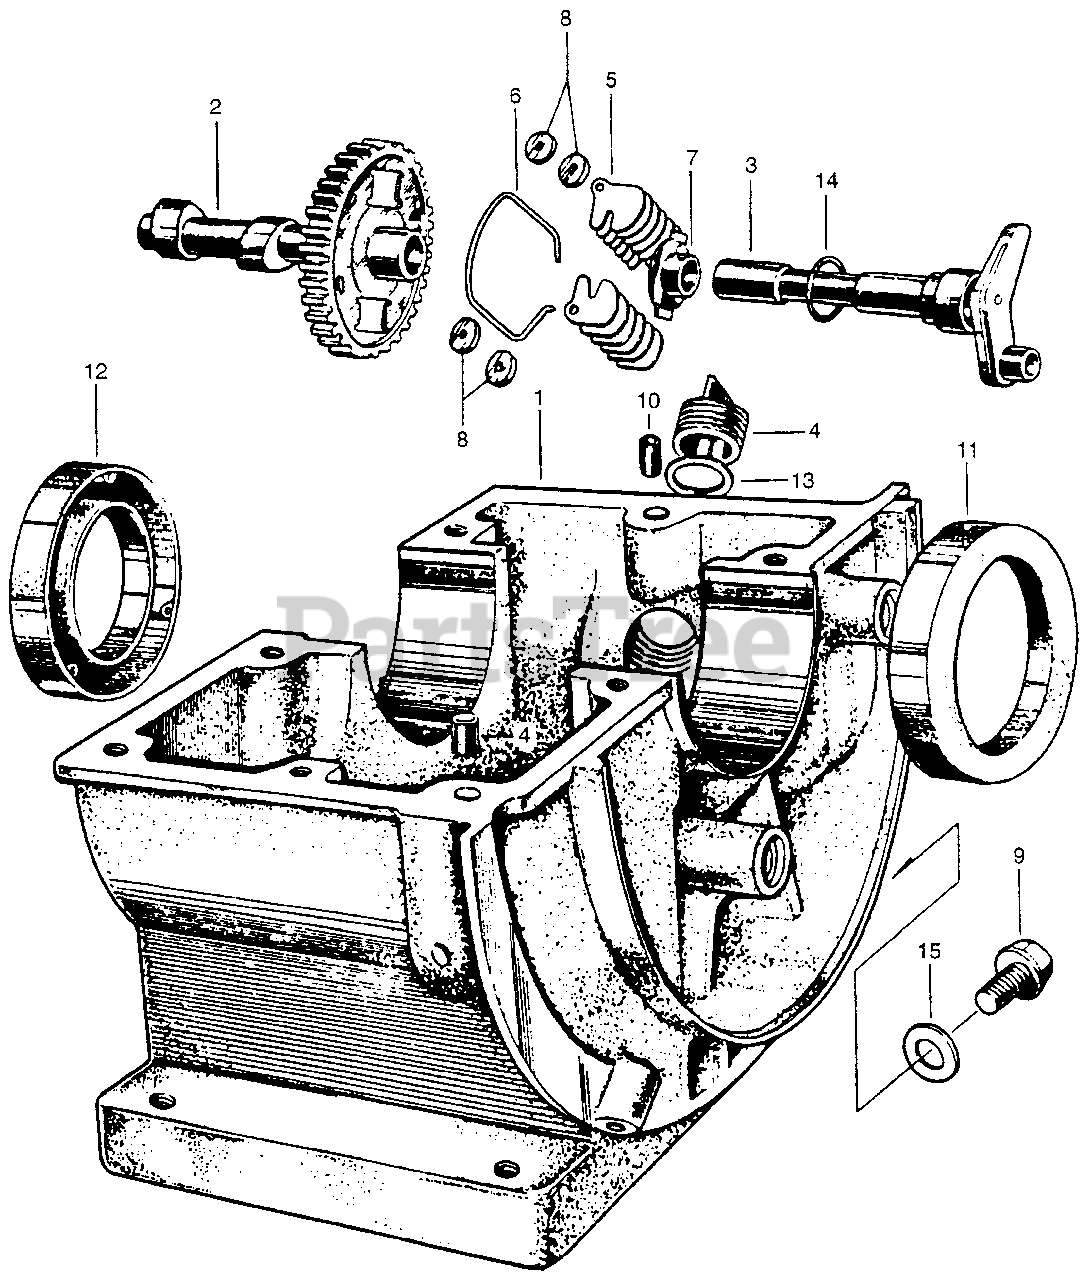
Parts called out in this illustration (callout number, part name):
1	PAN, OIL
3	CENTER, CAMSHAFT (NOT AVAILABLE)
4	CAP, OIL (YELLOW)
5	WEIGHT, GOVERNOR
6	CENTER, GOVERNOR WEIGHT
7	SLIDER, GOVERNOR
8	COLLAR, DISTANCE
9	BOLT, DRAIN PLUG
10	PIN, KNOCK (8.5X11) (NOT AVAILABLE)
11	OIL SEAL (PJ255510) (NOT AVAILABLE)
12	OIL SEAL (30X65X10) (NOT AVAILABLE)
13	O-RING (26X2.7)
14	O-RING (20X2)
15	WASHER, DRAIN PLUG (12MM)
